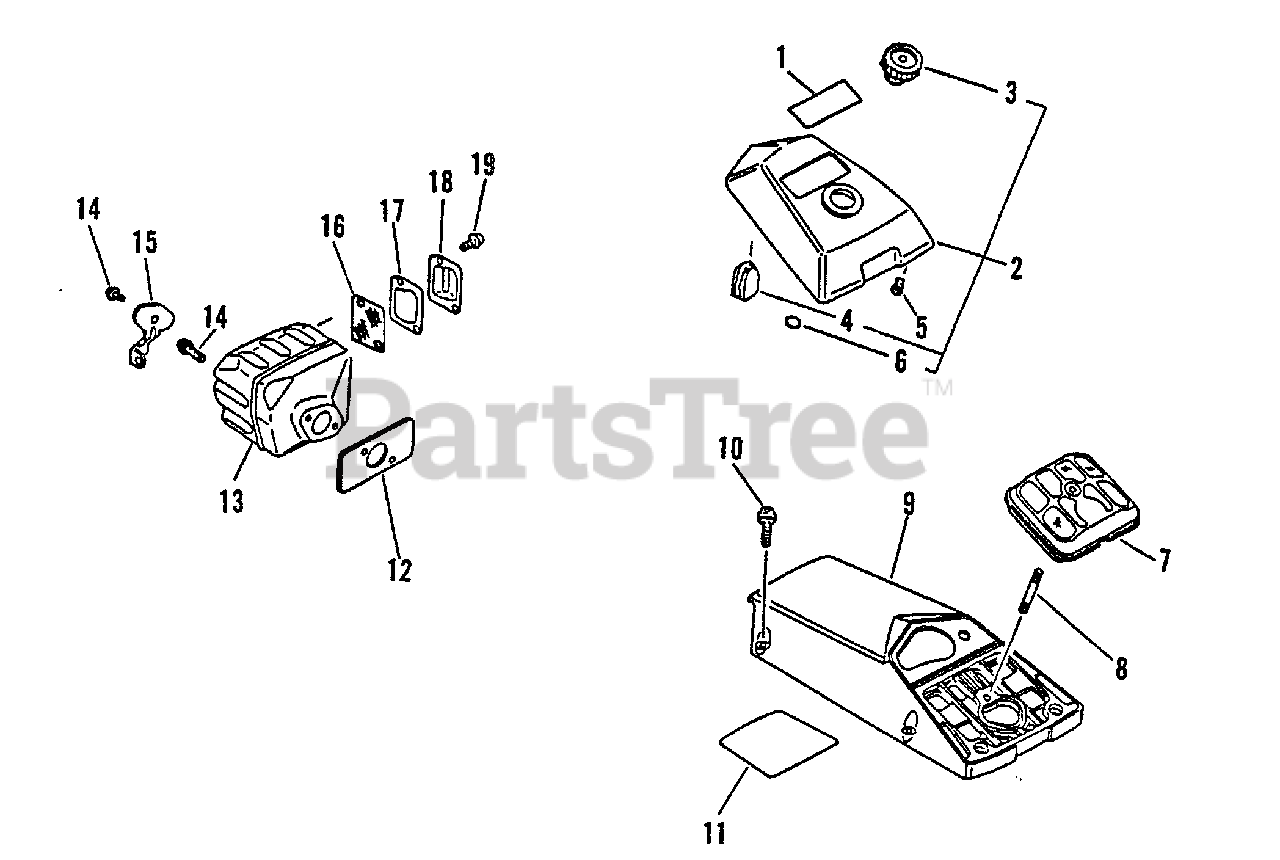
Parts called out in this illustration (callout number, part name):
1	LABEL - MODEL
2	COVER, AIR FILTER
3	WINGNUT
6	O-RING P-11
7	FILTER, AIR
9	COVER, ENGINE
10	SCREW 5×20
13	MUFFLER
14	SCREW 5×10
15	BRACKET, MUFFLER
16	SCREEN, SPARK ARRESTER
17	GASKET, MUFFLER
18	COVER, MUFFLER
19	SCREW 4×8
